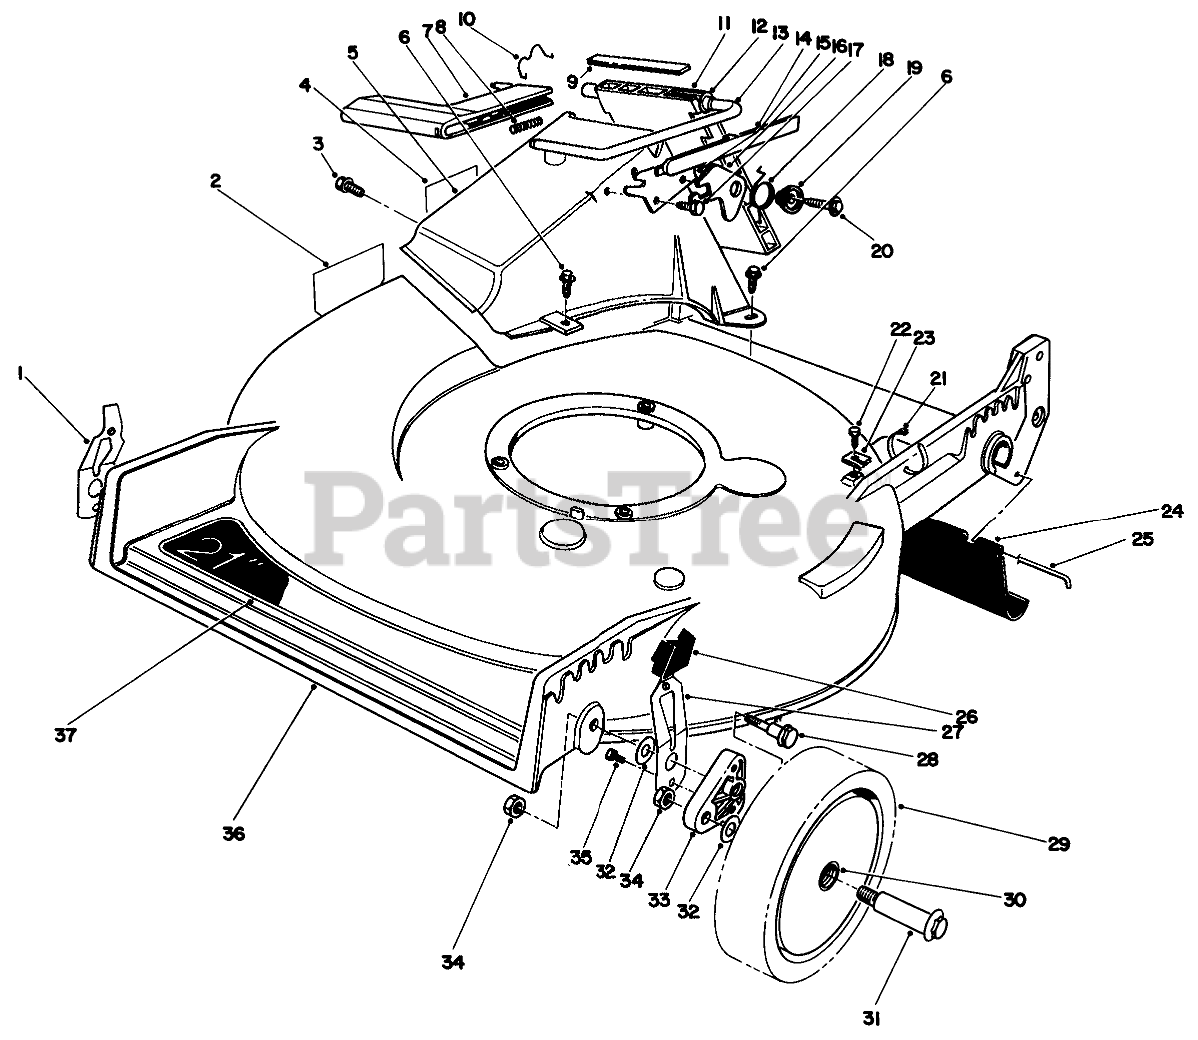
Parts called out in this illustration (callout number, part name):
1	RH SPRING ARM ASSEMBLY
2	DECAL-DANGER
3	SCREW AND WASHER ASM
4	DECAL - DANGER
5	Tunnel-Discharge (Incl. Ref. #4)
6	SCREW-HWH
7	Handle-Door
8	Spring
9	Cover-Door
10	DOOR RET SPRING
11	Door-Discharge
12	BUSHING-NYLON
13	DOOR ROD +
14	Cover-Handle
15	DOOR LATCH PLATE
16	SAFETY LATCH
17	SCREW-PLASTITE
18	TORSION SPRING
19	DOOR SPACER
20	SCREW-HWH
21	TIE-CABLE
22	SCREW-HWHTF
23	CLAMP-CABLE
24	SHIELD-TRAILING
25	ROD-SHIELD
26	KNOB-ARM
27	LH SPRING ARM ASSEMBLY
28	SCREW-SHOULDER
29	Wheel & Tire Assembly (Incl. Ref. #30)
30	BUSHING
31	WHEEL BOLT
32	WASHER
33	ARM-PIVOT, FRONT
34	Nut
35	SCREW-HWH
36	Housing Assembly (Incl. Ref. #2)
37	DECAL - DECK
